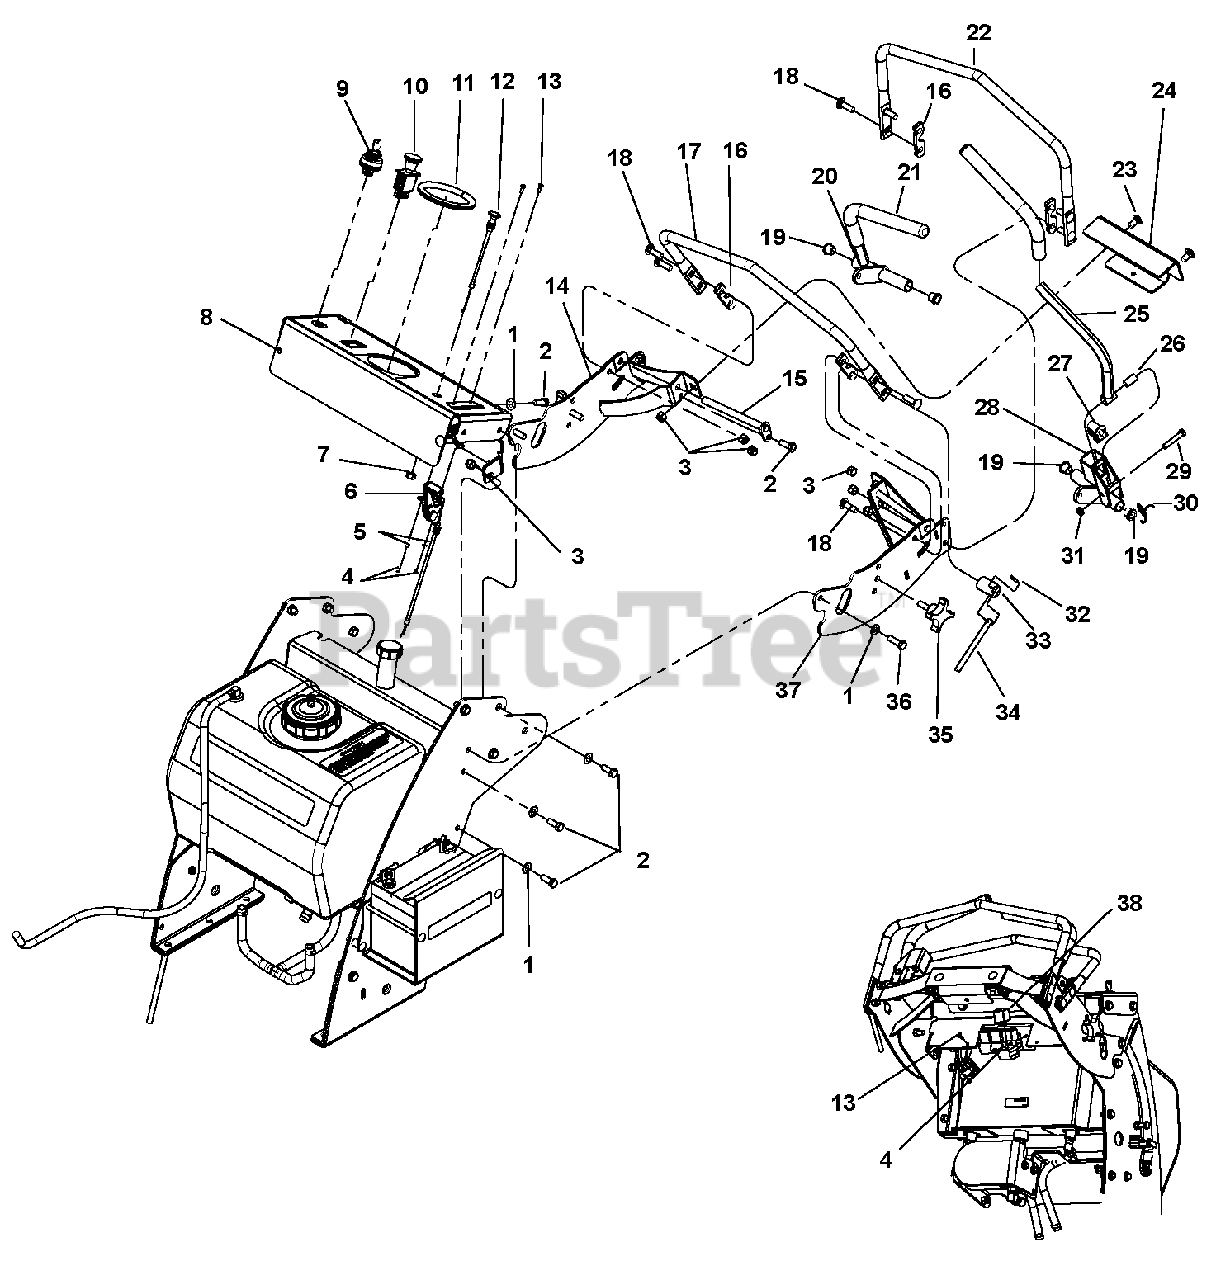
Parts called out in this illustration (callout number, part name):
1	Washer, .406 x .813 x .065 Flat
2	Bolt, .38-16 x 1.00 Hex Grade 5
3	Locknut, .38-16 Nyloc
4	Nut, 8-32 Standard Hex
5	Washer, #8 Medium Spring Lock
6	Cable, Throttle - 49.5"
7	Nut, .38-24 Standard Hex (988402, 403)
8	Console Assembly w/ Decal
9	Switch, Key - 3 Postion (988402, 403)
10	Switch, PTO Engagement
11	Trim, Rubber Edge 12"
12	Cable, Choke 48"
13	Screw, 8-32 x .50 Panhead Phillips
14	Weldment, RH Handle Mount 5 Deg.
15	Weldment, Pin and Lock
16	Shim, 5 Deg. Speed Bar
17	Handle, Support
18	Bolt, .38-16 x 1.25 G5 Round Head Square Neck
19	Bearing, Flange .500 x .625 x .500
20	Weldment, RH Drive Lever 5 Deg
21	Grip, Control
22	Handle, Support
23	Bolt-Round Head Square Neck .38-16 x .75 Grade 5
24	Plate, Handle Mount Link
25	Weldment, LH Drive Lever 5 Deg
26	Spacer, .330 x .500 x .980
27	Switch, Seat Over Ride (N.O.)
28	Weldment, LH Handle Mount
29	Bolt, .31-18 x 1.75 Hex Grade 5
30	Spring, Torque 1.00 x .062
31	Locknut, .3125-18 Nyloc
32	Pin, Spring
33	Base, Lock Lever
34	Lever, Lock
35	Knob, .38 x 1.25 - 4 Prong
36	Bolt, .38-16 x 1.25 Hex Grade 5
37	Weldment, LH Handle Mount 5 Deg
38	Relay, ISO Mini Electric (988402, 403)
39	Harness, Wire Non Electric (988400) (NS)
40	Harness, Wire, Electric (988402, 403) (NS)
